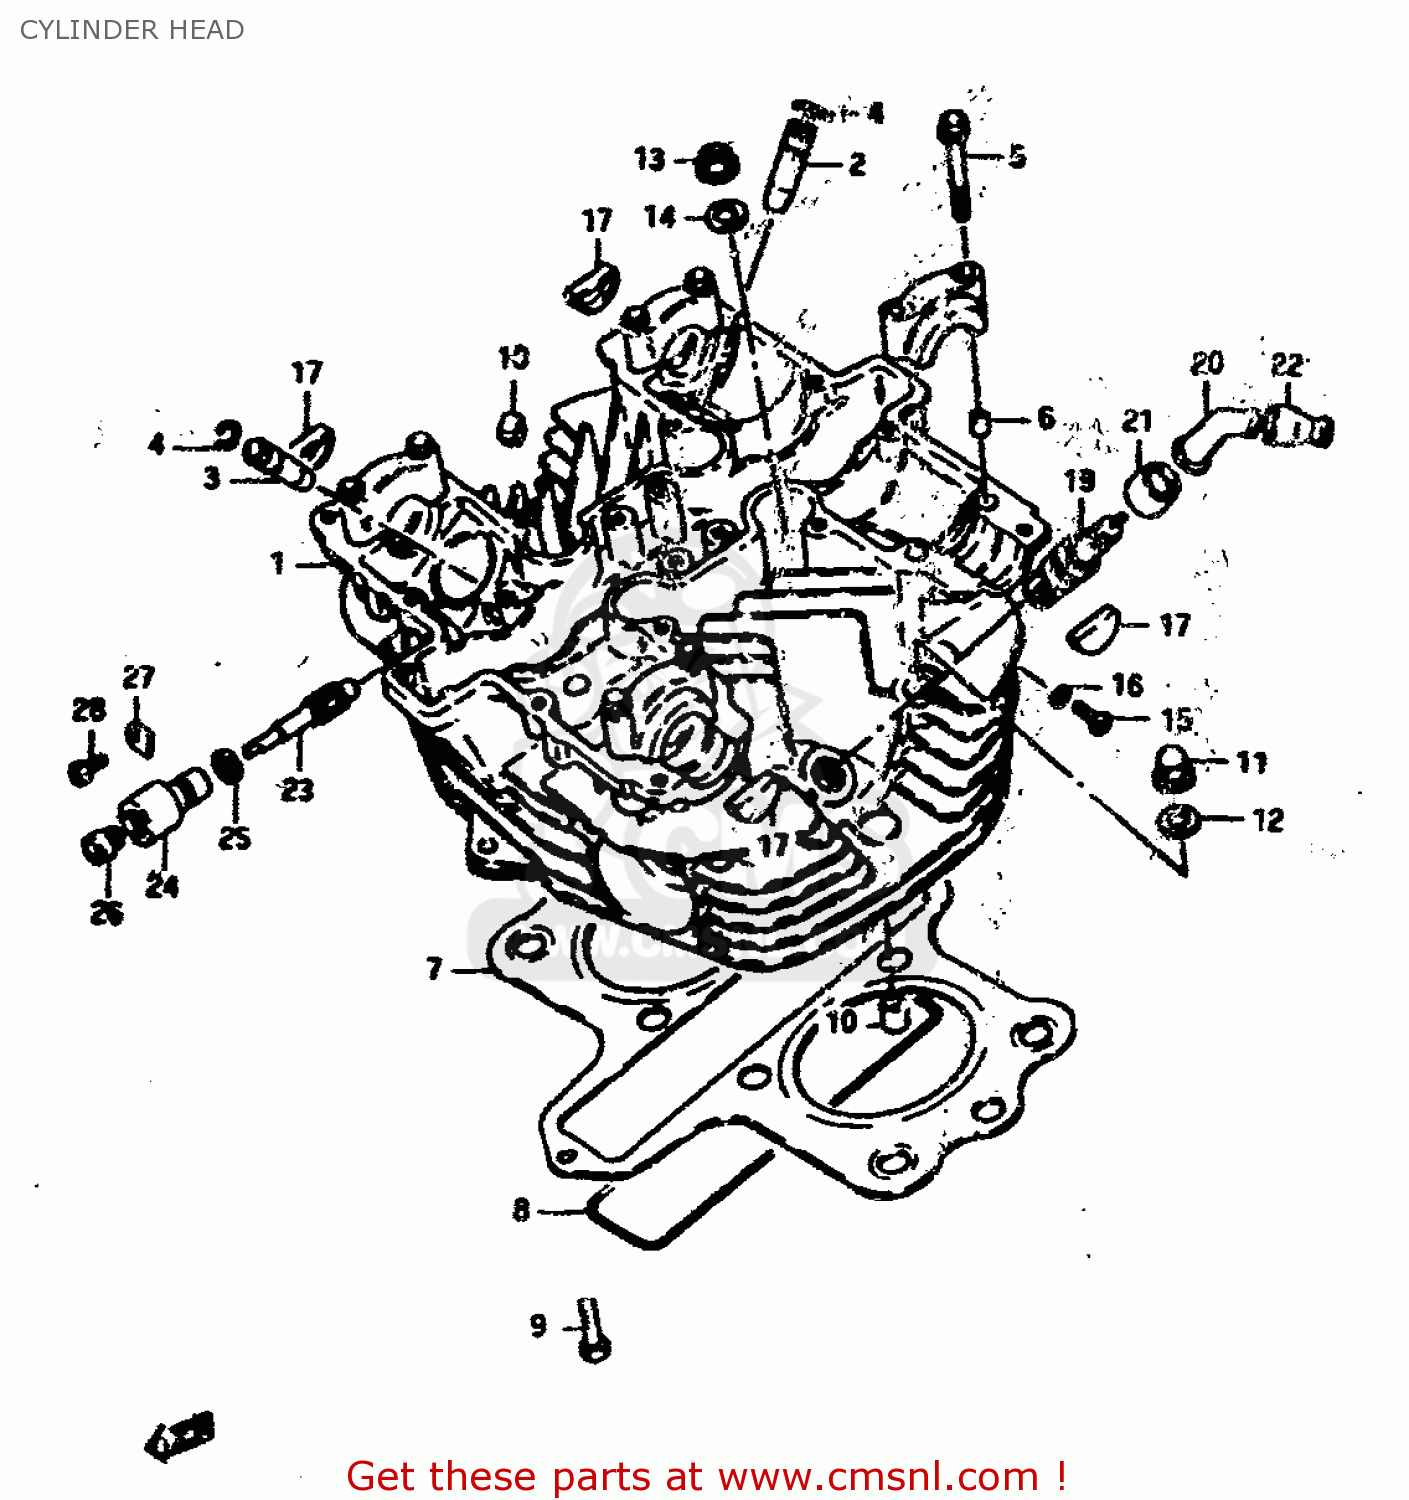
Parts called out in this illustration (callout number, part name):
1	HEAD SET,CYLINDER
2	GUIDE,VALVE
3	GUIDE,VALVE
4	RING,SNAP
5	BOLT(6X39)
6	PIN(6.2X8X11)
7	GASKET,CYLINDER HEAD (MCA)
8	O RING(D:3,ID:26X157)
9	BOLT
10	PIN
11	NUT
12	GASKET(10.5X22X2) (NAS)
13	NUT
14	WASHER(10.5X22X2.3)
15	SCREW 5X20
16	GASKET(5.3X9.3X1.2) (NAS)
17	PLUG
18	PAD
19	PLUG,SPARK
20	CAP,SPARK PLUG
21	SEAL,SPARK PLUG
22	SEAL,SPARK PLU
23	GEAR,TACHOMETER DRIVEN
24	SLEEVE,TACHOMETER DRIVE
25	SEAL,TACHOMETER DRIVEN
26	SEAL
27	PLATE,TACH DRIVE GEAR SLEEVE
28	SCREW(5X12)
